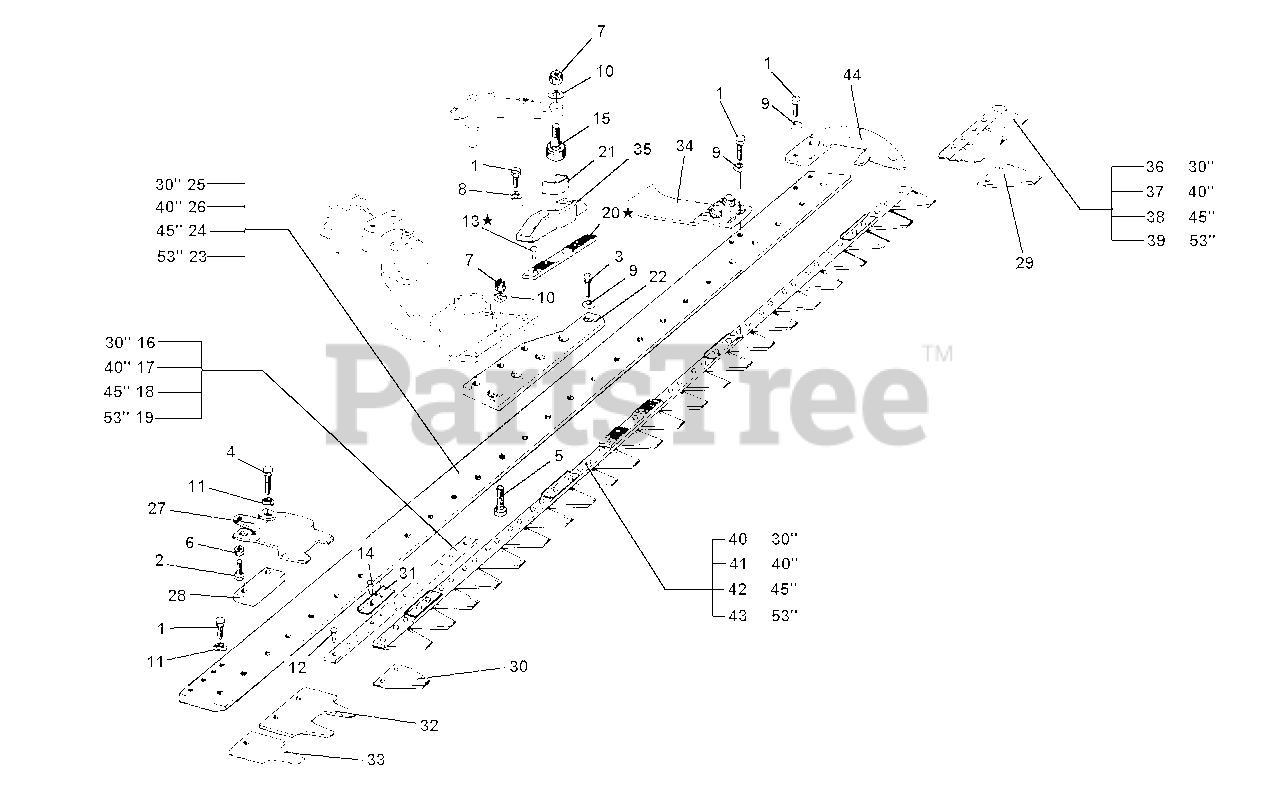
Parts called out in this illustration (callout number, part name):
1	SCREW M8X16
2	SCREW M8X20
3	SCREW M8X25
4	SCREW M8X35
5	SCREW M10X35
7	NUT, SELF LOCKING
8	WASHER, FLAT 8,4
9	SUPER WASHER 8
10	SUPER WASHER 10
11	WASHER, LOCK 8,4
12	RIVET 5.3X14
13	RIVET 5.3X18
14	RIVET 5.3X16
15	BLADE CONTROL PIN
16	BLADE STRIP 30"
17	BLADE STRIP 40"
18	BLADE STRIP 45"
19	BLADE STRIP 53"
20	PLATE FOR BLADE COUPLING
22	BAR COUPLING
23	SLIDE FOR CUTTER BAR 53"
24	SLIDE FOR CUTTER BAR 45"
25	SLIDE FOR CUTTER BAR 30"
26	SLIDE FOR CUTTER BAR 40"
27	BLADE HOLDER
28	BLADE GUIDE BLOCK
29	INDIVIDUAL BLADE, SERATED
30	INDIVIDUAL BLADE, SMOOTH
31	PLATE FOR CLEANING
32	DOUBLE FINGER
33	SINGLE FINGER
35	BLADE COUPLER
36	BLADE ASSEMBLY, SERATED 30"
37	BLADE ASSEMBLY, SERATED 40"
38	BLADE ASSEMBLY, SERATED 45"
39	BLADE ASSEMBLY, SERATED 53"
40	BLADE ASSEMBLY, SMOOTH 30"
41	BLADE ASSEMBLY, SMOOTH 40"
42	BLADE ASSEMBLY, SMOOTH 45"
43	BLADE ASSEMBLY, SMOOTH 53"
44	END GUARD, PAIR
